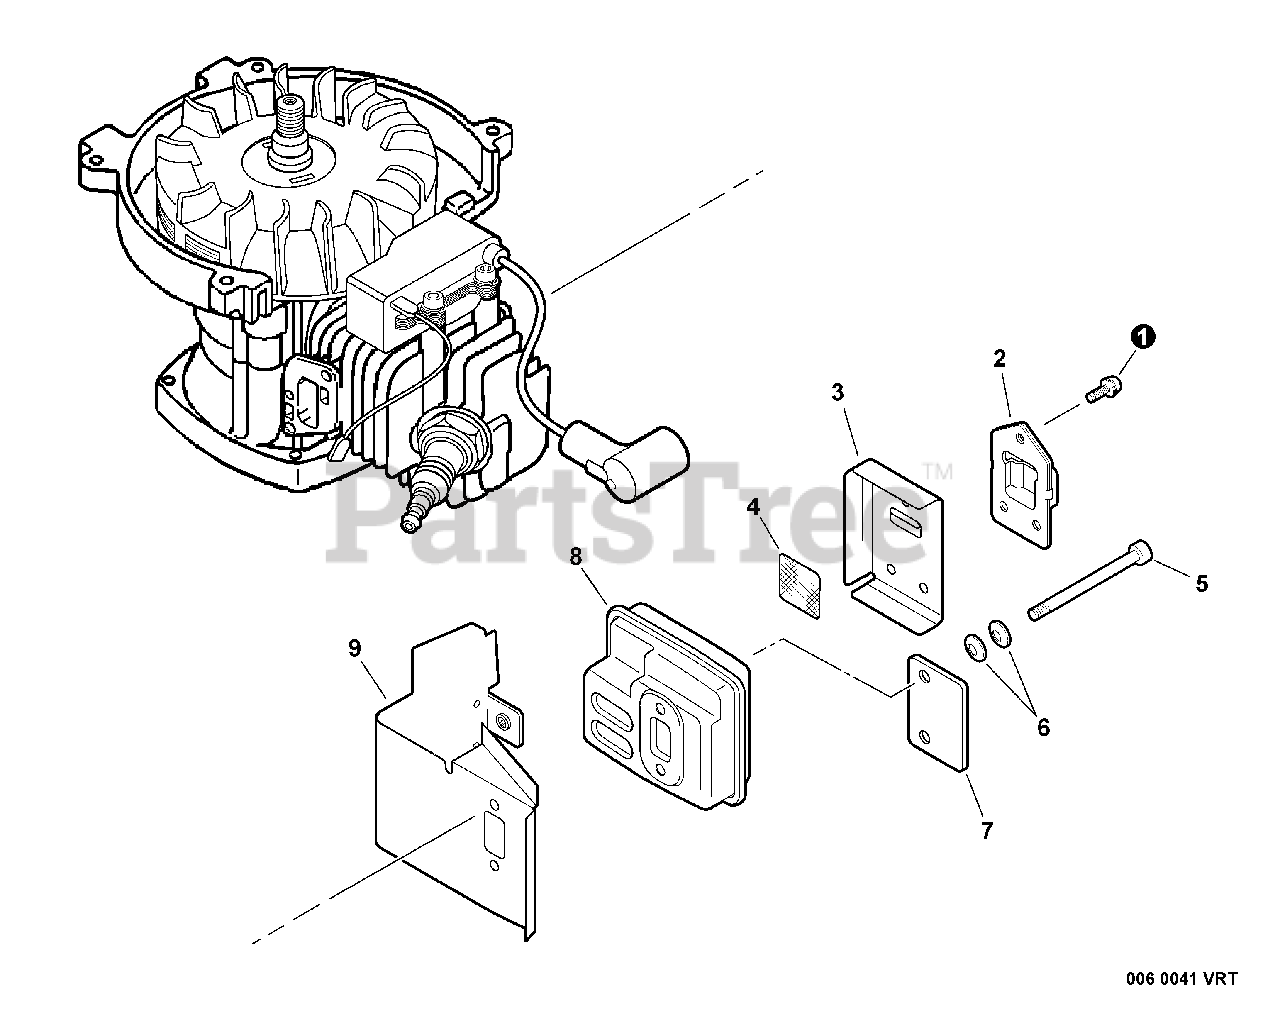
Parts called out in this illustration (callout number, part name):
1	SCREW 4×12
2	GUIDE, EXHAUST
3	GASKET, EXHAUST
4	SCREEN, SPARK ARRESTER
5	BOLT 5×55
6	CONICAL WASHER
7	PLATE, EYE
8	MUFFLER
9	HEAT SHIELD, EXHAUST
